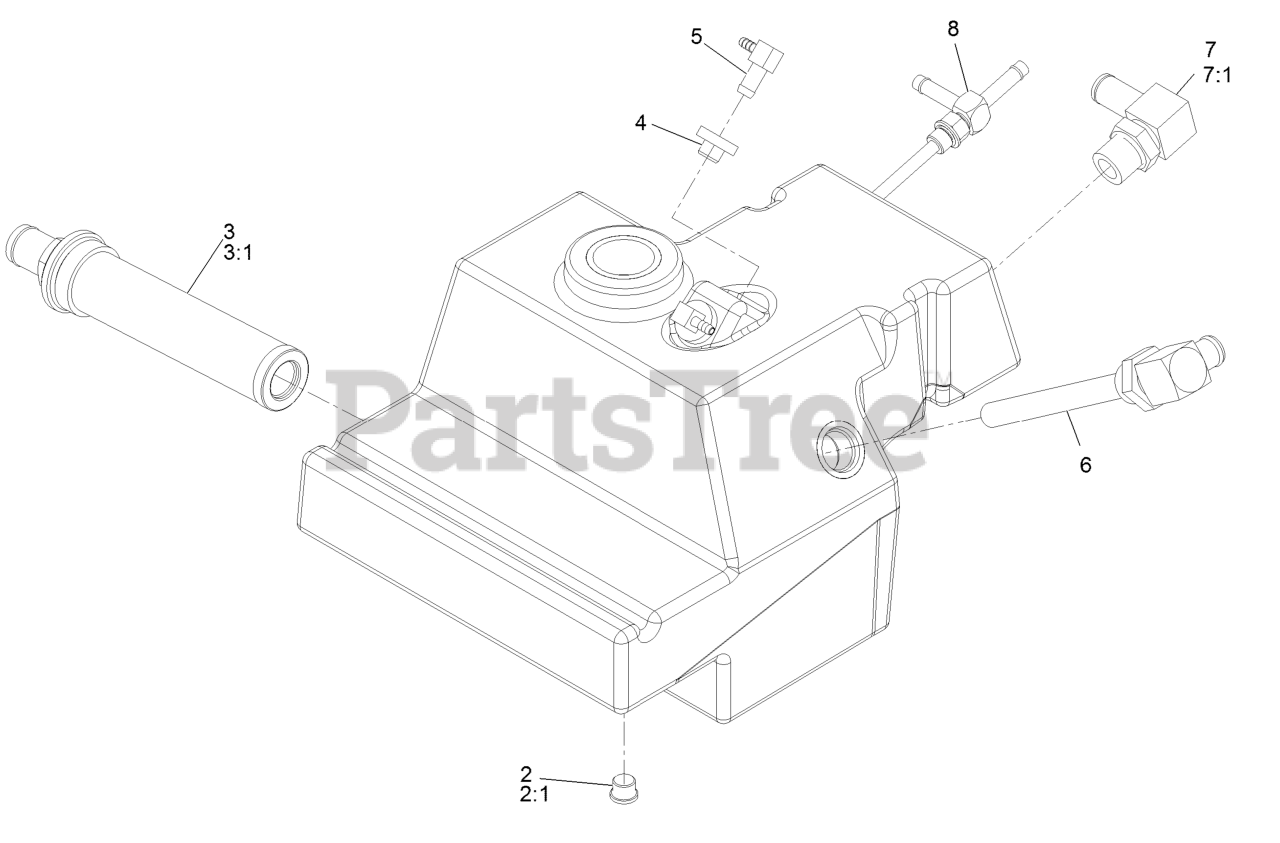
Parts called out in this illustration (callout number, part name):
2	Plug-Hex, Hollow
2:1	O-Ring
3	Tank Strainer ASM
4	Bushing
5	Fitting-Elbow, 90 DEG
6	Fitting-Standpipe
7	Fitting-Elbow, 90
7:1	O-Ring
8	Fitting-Tee, Drop Tube
